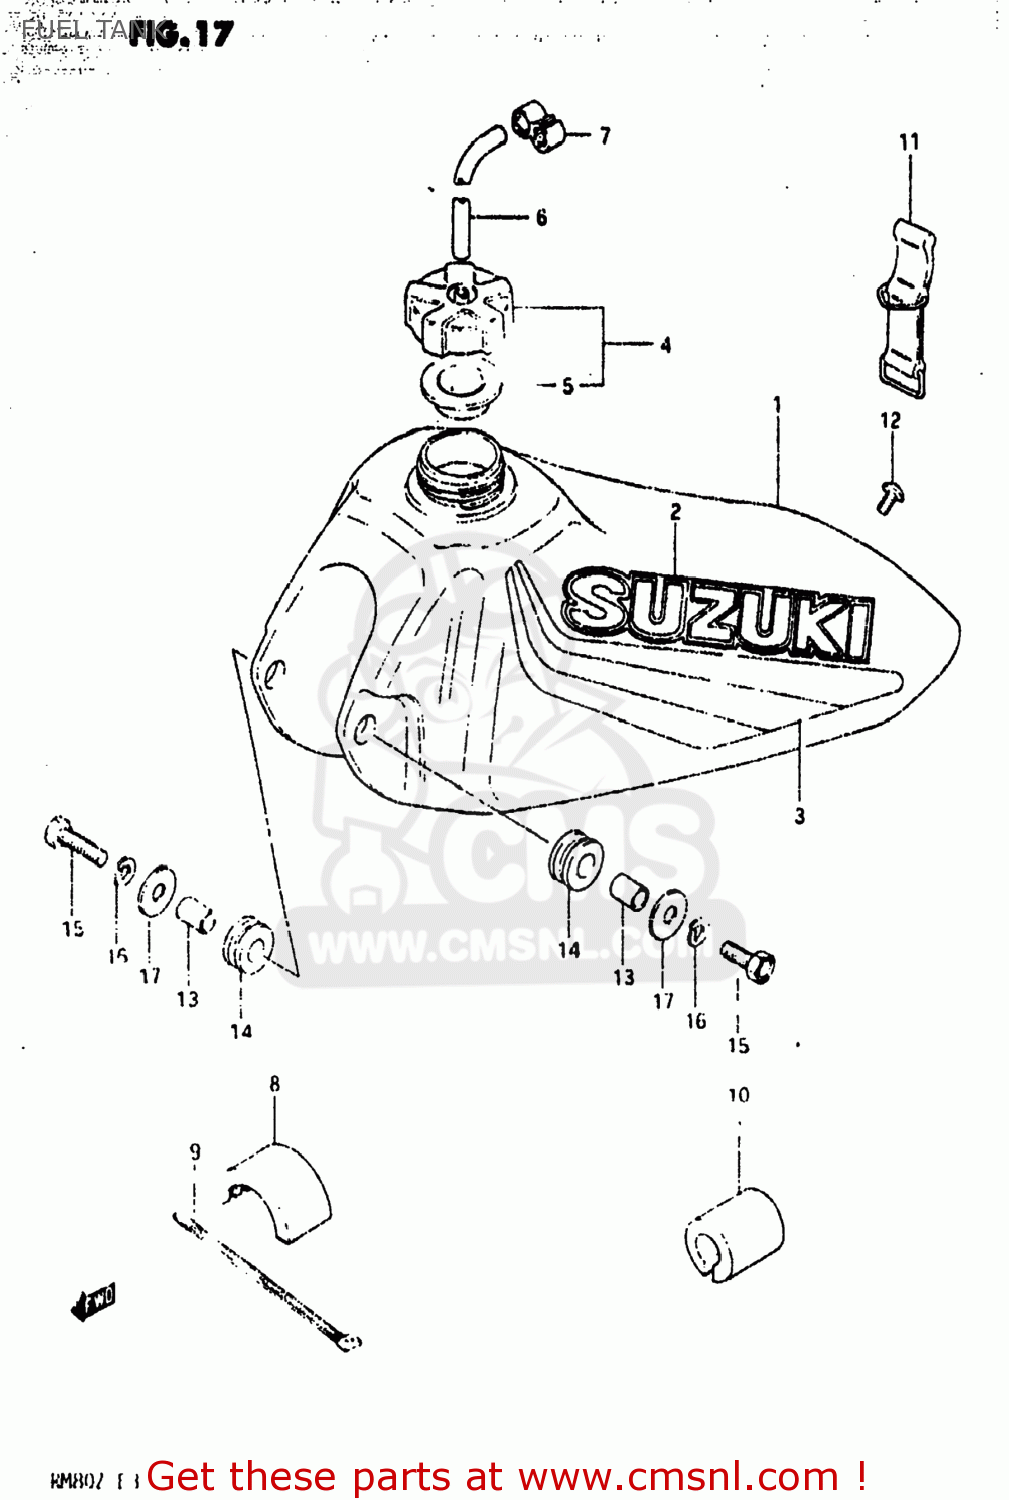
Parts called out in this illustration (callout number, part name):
1	TANK ASSEMBLY,FUEL
2	EMBLEM
3	TAPE SET,FUEL TANK
4	CAP,FUEL TANK FILLER
5	GASKET,FUEL TANK CAP (NAS)
6	HOSE
7	CLAMP,FUEL TANK BREATHER HOSE
8	CUSHION,FUEL TANK UPR FR
9	CLAMP
10	CUSHION,FUEL TANK UPR RR
11	BAND
12	SCREW (6X15)
13	SPACER (6.8X10X11.5)
14	CUSHION
15	BOLT
16	LOCK WASHER
17	WASHER(6.5X18X1)
